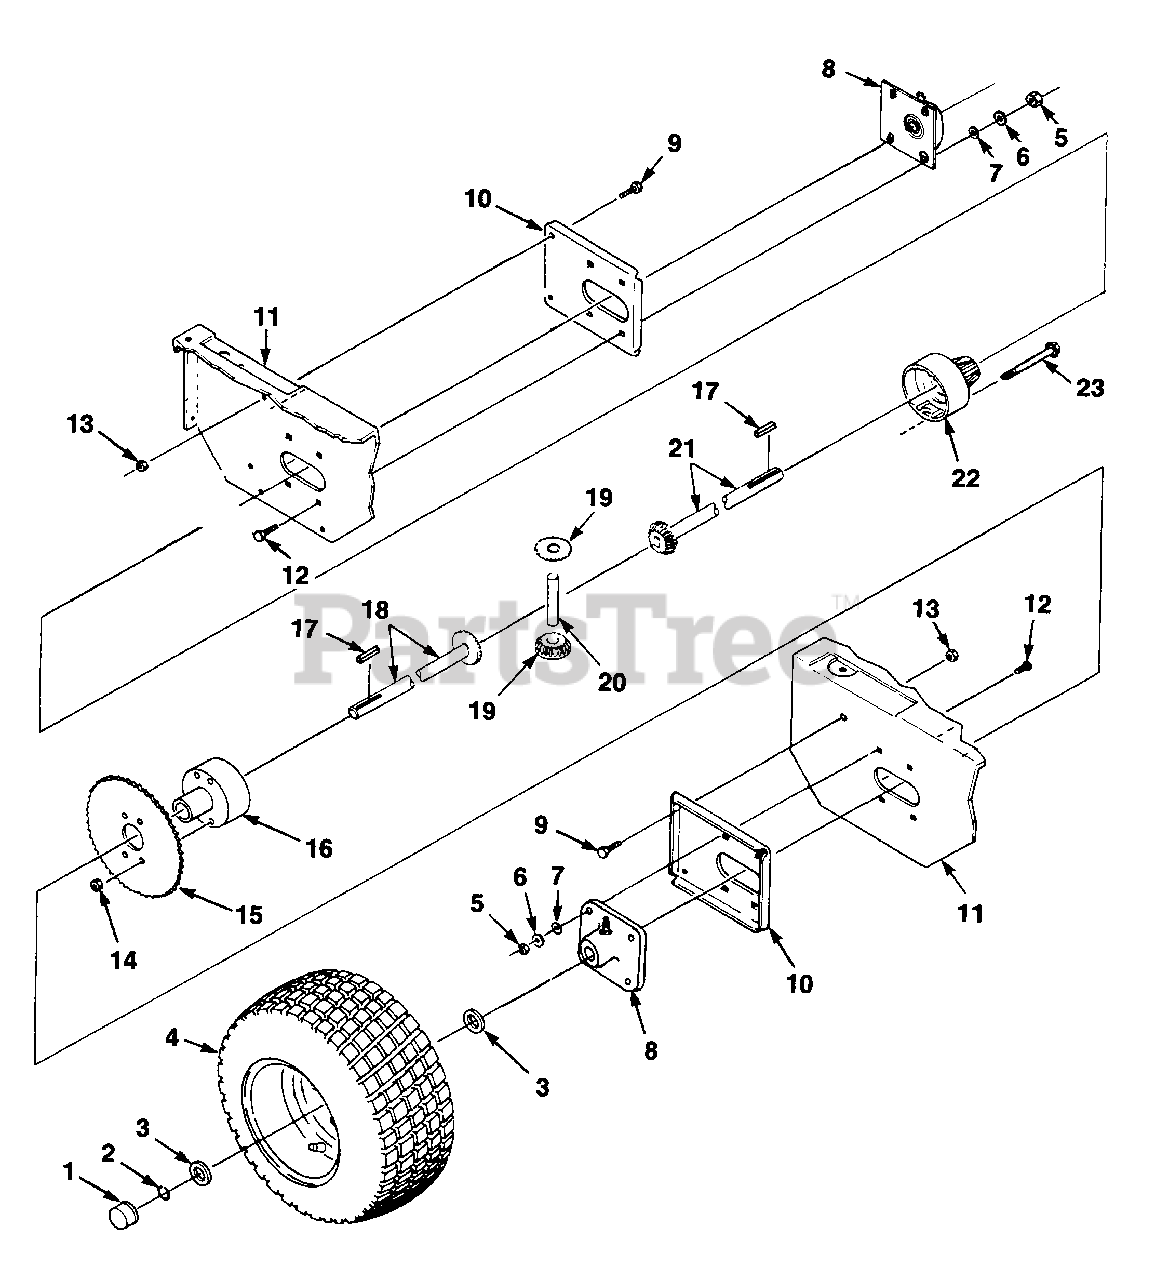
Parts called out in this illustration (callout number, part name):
2	RING- Retaining
3	SPACER- Axle
5	Nut (Hex Locking)
7	Superseded by PS84010
10	SUPPORT- Frame
12	Superseded by 80095
13	Nut - hex 1/4-20 lock
18	AXLE GEAR(RE-830) TBO
